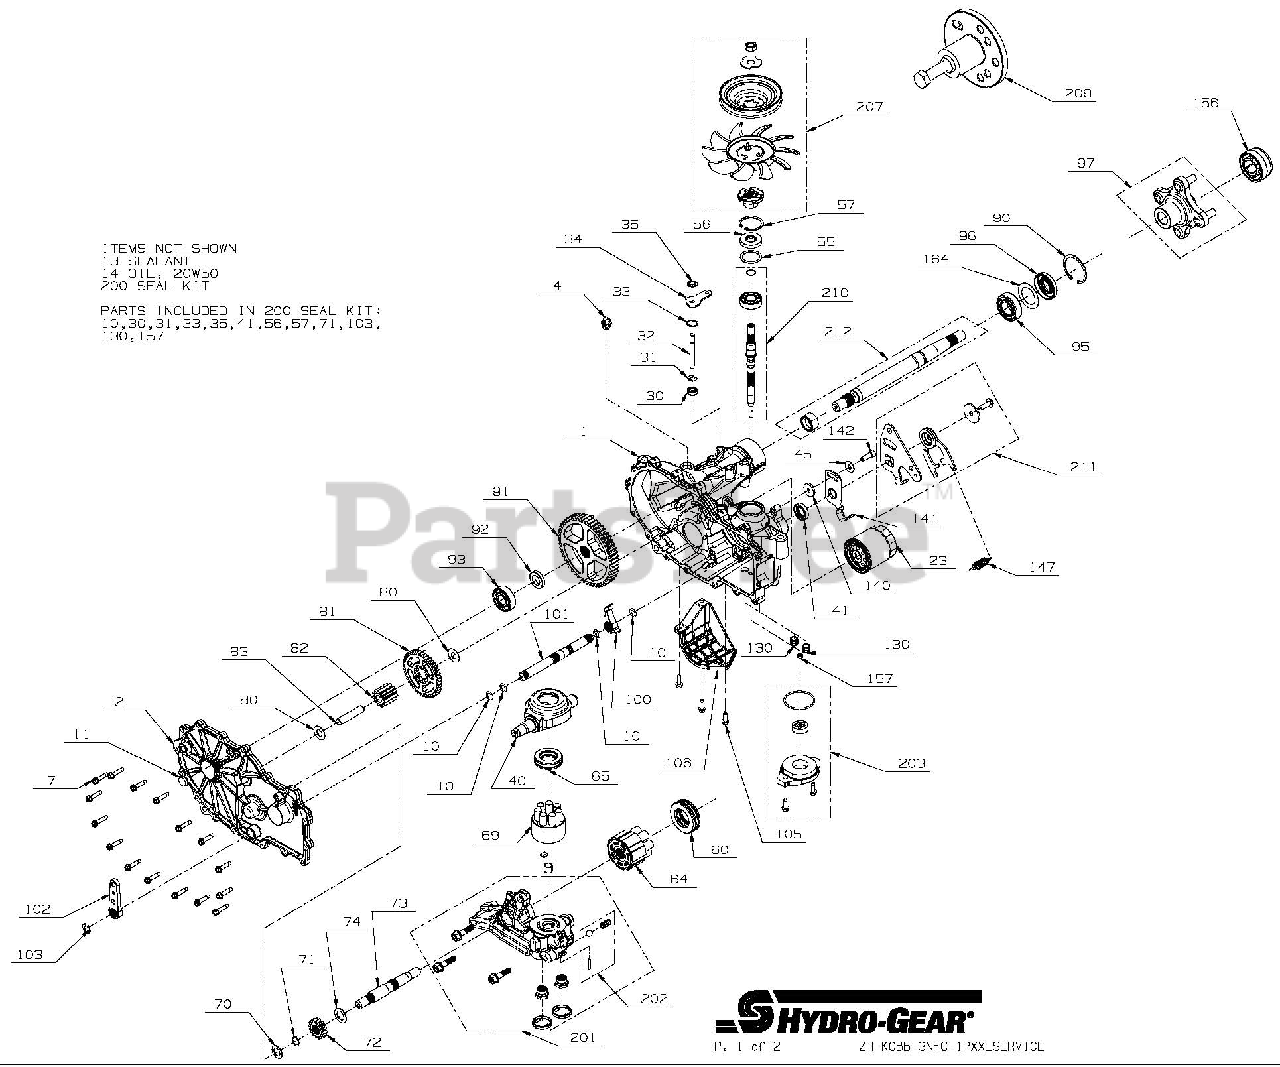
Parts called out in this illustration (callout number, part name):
1	KIT, MAIN HOUSING RH CHARGE, CONTROL
2	KIT, COVER SIDE RH
4	PLUG, 9/16-18 (PLASTIC)
7	SCREW,HEX WASHER 1/4-20X1.125
13	SEALANT TUBE 10.1OZ.
23	OIL FILTER, TRANSMISSION
30	SEAL, LIP .375X.75X.25
31	RING. RETAINING
33	RING, RET .750
34	ARM, BYPASS
35	RING, RTNG .
40	TRUNNION, SWASHPLATE
41	SEAL, LIP 18X32X7
45	WASHER
55	WASHER 1.23X1.56X.04
56	SEAL, LIP 17X40X7
57	RING, RET 1.56 INT
60	HG THRUST BEARING (51462)
64	HG 16CC CYLINDER BLOCK (71579)
65	BEARING. THRUST 30 X 52 X 13
69	ASSY, BLOCK 7 PISTON
70	WASHER .63X1.0X.05
71	RING, RET 62 EXT
73	SHAFT, MOTOR
74	WASHER .71 X 1.16 X .04
80	WASHER .5X1.0X.032
83	JACK SHAFT (PIN)
90	RING, RETAINING
95	BEARING, BALL 25.4 X 52 X 15
96	SEAL, LIP
97	KIT, HUB, 4 BOLT
100	PAWL, BRAKE
101	KIT, BRAKE SHAFT
102	HANDLE, ACTUATING
105	HFHCS 1/4-20X.75
106	GUARD, FILTER, RH
140	SPACER
141	ARM, NEUTRAL RIGHT
142	SHCS 5/16-24X1 PATCH
147	SPRING, HYDROGEAR P/N 51833
156	CAP, AXLE
157	KIT, GEROTOR SEAL
164	WASHER, 1.355 x 2.035 x .021 FLAT
200	KIT, SEAL
201	KIT, CENTER SECTION RH CHARGE
202	KIT, CHARGE RELIEF
203	KIT, CHARGE PUMP 71411
207	FAN PULLEY KIT 4.5X1.625
209	HUB PULLER 4 BLT HYDGEAR 71459
210	INPUT SHAFT 2800 HYDGEAR 71442
211	KIT, RTN CCW
212	KIT, SHAFT AXLE
